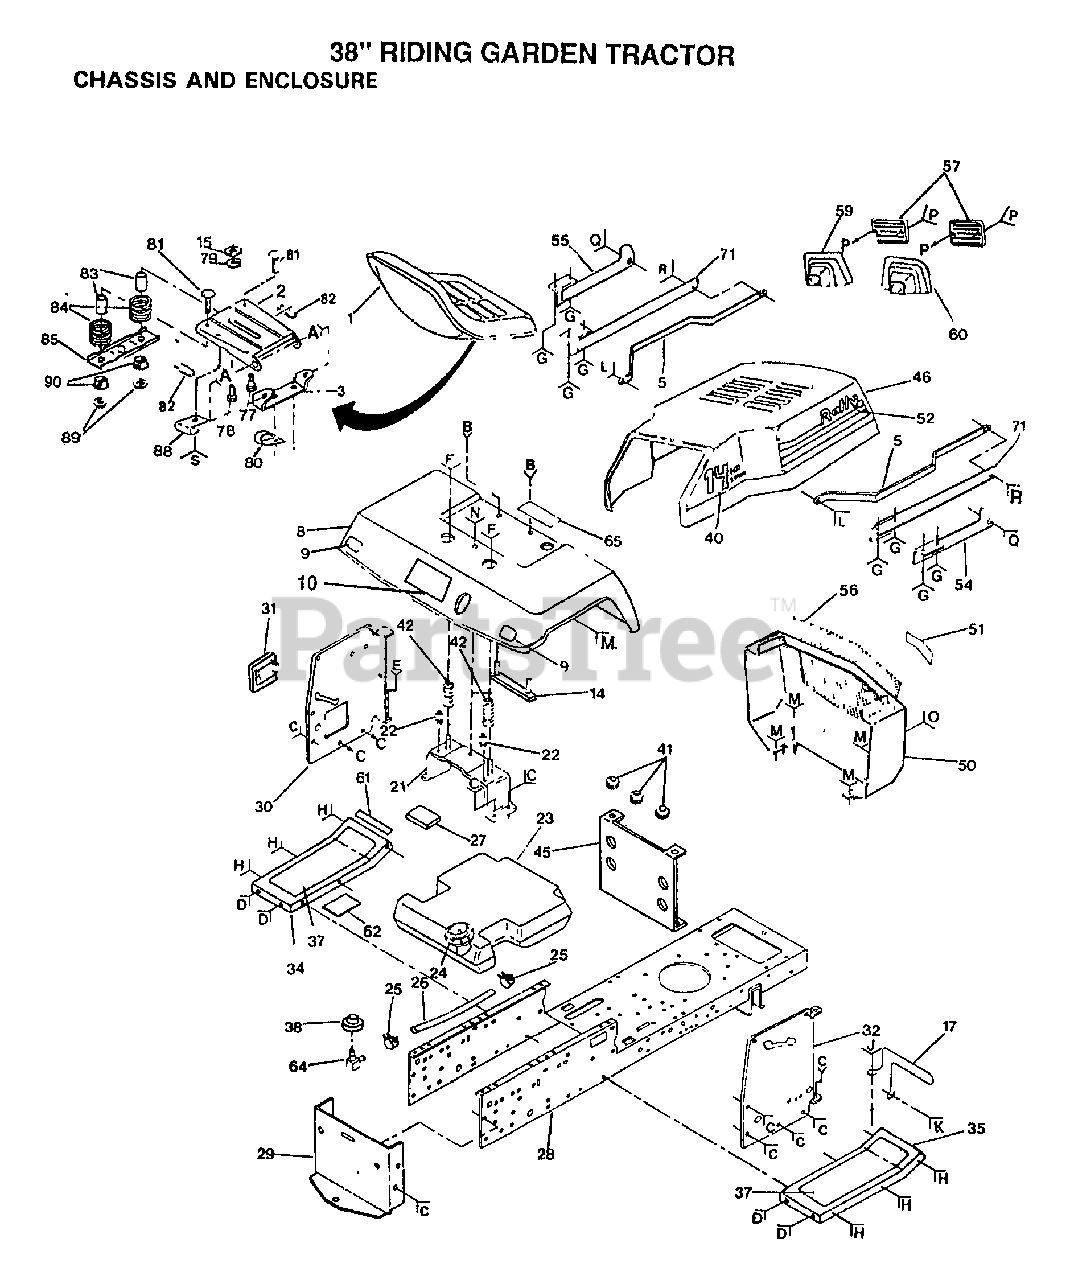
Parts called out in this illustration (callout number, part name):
9	REFLECTOR-TAIL YT
15	WASHER
17	GUARD MUFFLER HYT
22	NUT-PUSH YT
27	PAD-SPACER LT
28	CHASSIS ASSY
31	COVER ACCESS
32	PANEL DASH RH YT
34	FOOTREST - L.H.
35	FOOTREST - R.H.
37	PAD FOOTREST T
38	BUSHING OUTLET T
41	SNAP BUSHING T
54	STRAP ASSY T
55	STRAP ASSY T
56	SCREEN GRILL GTV
64	FUEL TANK STEM GT
71	STRAP ASSY-REAR T
78	BOLT
79	LOCKWASHER
80	CLIP T
81	BOLT
82	STRIP FORM
83	SPACER SPLIT
84	SPRING
85	BRKT SWITCH
89	NUT T
90	BUSHING
